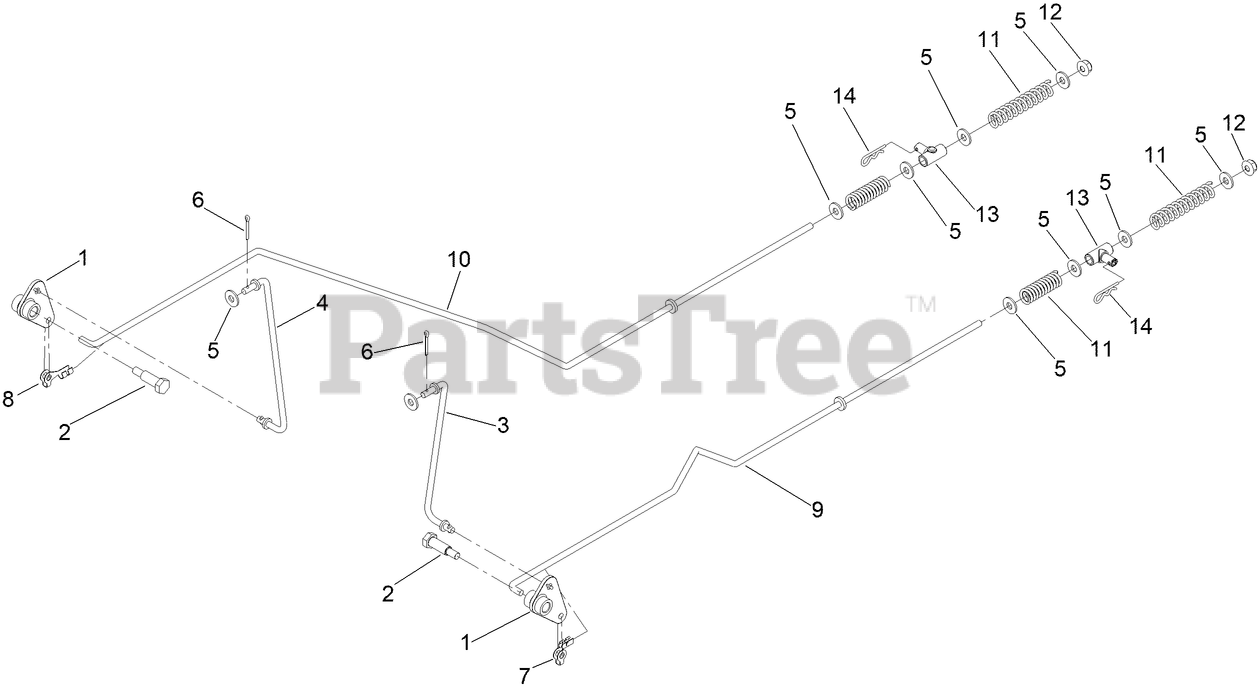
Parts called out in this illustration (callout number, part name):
1	BELLCRANK
2	BOLT - SHOULDER
3	LINK-BRAKE, LH
4	LINK-BRAKE, RH
5	WASHER
6	PIN-COTTER
7	CLIP, ROD, LH, 7L, 1/4IN
8	CLIP, ROD, RH, 7R, 1/4IN
9	ROD-BRAKE LH
10	ROD-BRAKE, RH
11	SPRING-RETURN, NEUTRAL
12	NUT-FLANGE, NI
13	MOUNT-PIVOT
14	PIN-HAIR
